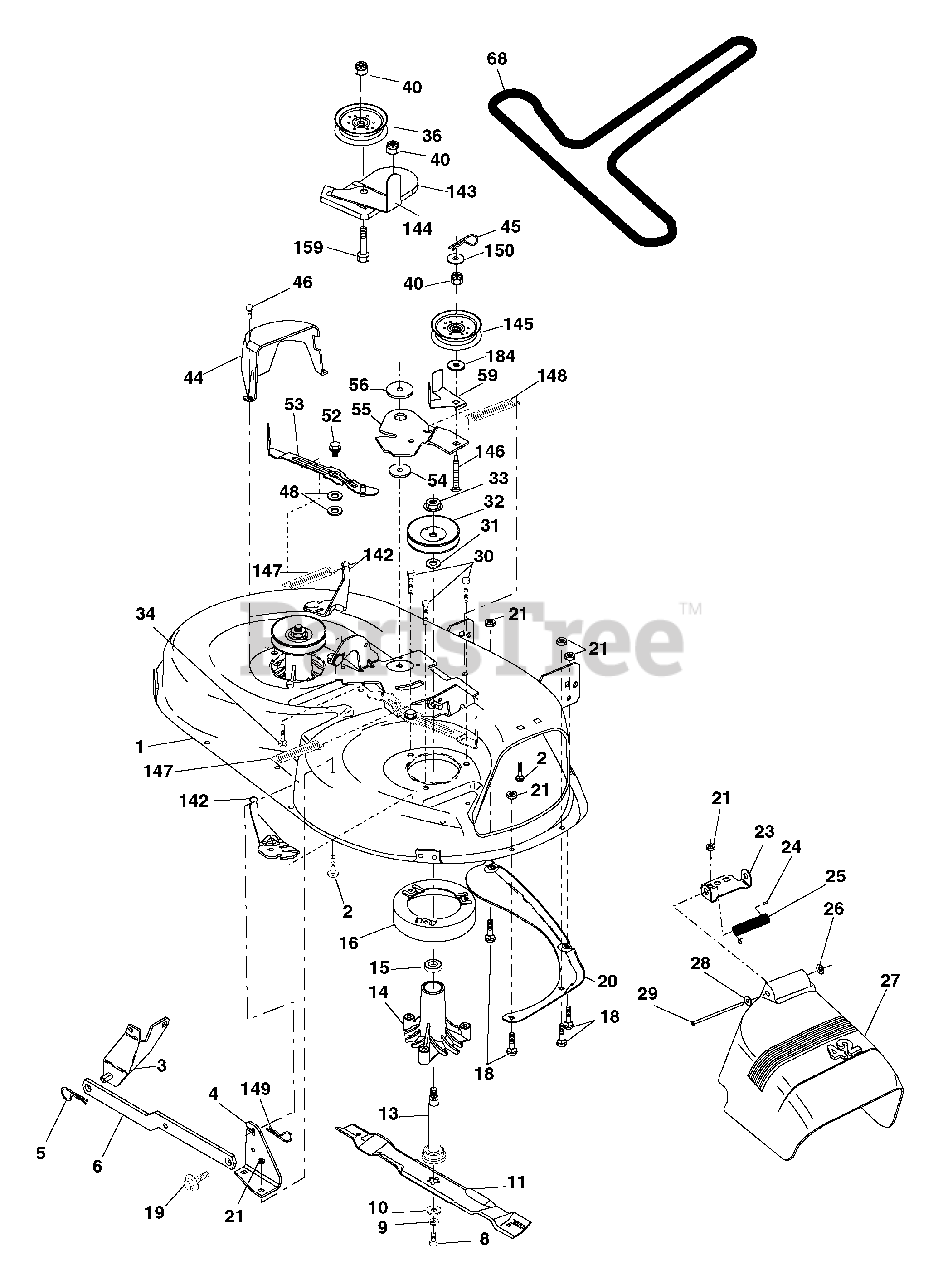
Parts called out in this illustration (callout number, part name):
1	Mower Deck Assembly, 42"
2	Bolt
3	Bracket Asm Fr. Sway Bar 3/42
4	Bracket Asm Deck 42" Sway Bar
5	Retainer Spring
6	Bar Sway Deck
8	Bolt 3/8-24 x 1.25 Gr. 8 patched
9	Washer, Lock
10	Washer, Hardened (The following Blades are available)
11	Blade Mower 42" Hi-Lift
13	Shaft Assembly, Mandrel, Vented
14	Housing, Mandrel, Vented
15	Bearing, Ball, Mandrel
16	Stripper, Mandrel Deck
18	Bolt, Carriage 5/16-18 x 5/8
19	Bolt, Shoulder
20	Baffle, Vortex
21	Nut
23	Bracket, Defl ector Mower 42"
24	Cap, Sleeve 80 x 112 Blk Mower
25	Spring, Torsion, Defl ector 2 52
26	Nut, Push Phos & Oil
27	Shield, Defl ector 42" Blk
28	Washer 11/32 x 5/8 x 16 Ga.
29	Rod, Hinge 42" 6 75 W/G
30	Screw Thdrol
31	Washer, Spacer Mower Vented
32	Pulley, Mandrel
33	Nut, Toplock
34	Bolt Carr SH 3/8-16 x 1-1/2 Gr.5
36	Pulley, Idler, Flat
40	Nut Lock 3/8-16
44	Guard, Mandrel, LH
45	Retainer
46	Screw, Thdrol 1/4-20 x 5/8 T
48	Washer, Hardened
52	Bolt, Shoulder 5/16-18 unc
53	Arm Assembly, Pad, Brake
54	Washer, Hardened
55	Arm, Idler
56	Spacer, Retainer
59	Guard TUV Idler
67	Knob Round
68	V-Belt, 42" Mower
142	Arm Spring Brake Mower
143	Bracket Arm Idler 42"
144	Keeper Belt 42" Clutch Cable
145	Pulley Idler Flat
146	Bolt Carriage Idler
147	Spring Extension
148	Spring Return Idler
149	Retainer Spring Yellow
150	Washer 9/32 x 3/4 x 10 Ga.
152	Clutch Cable 42"
158	Screw Hex Thd Cut 1/4-20 x 1/2
159	Bolt Rdhd Sqn 3/8-16 unc x 1-3/4
184	Washer 13/32 x 7/8 x 10 Ga.
185	Head Asm Cable Clutch
